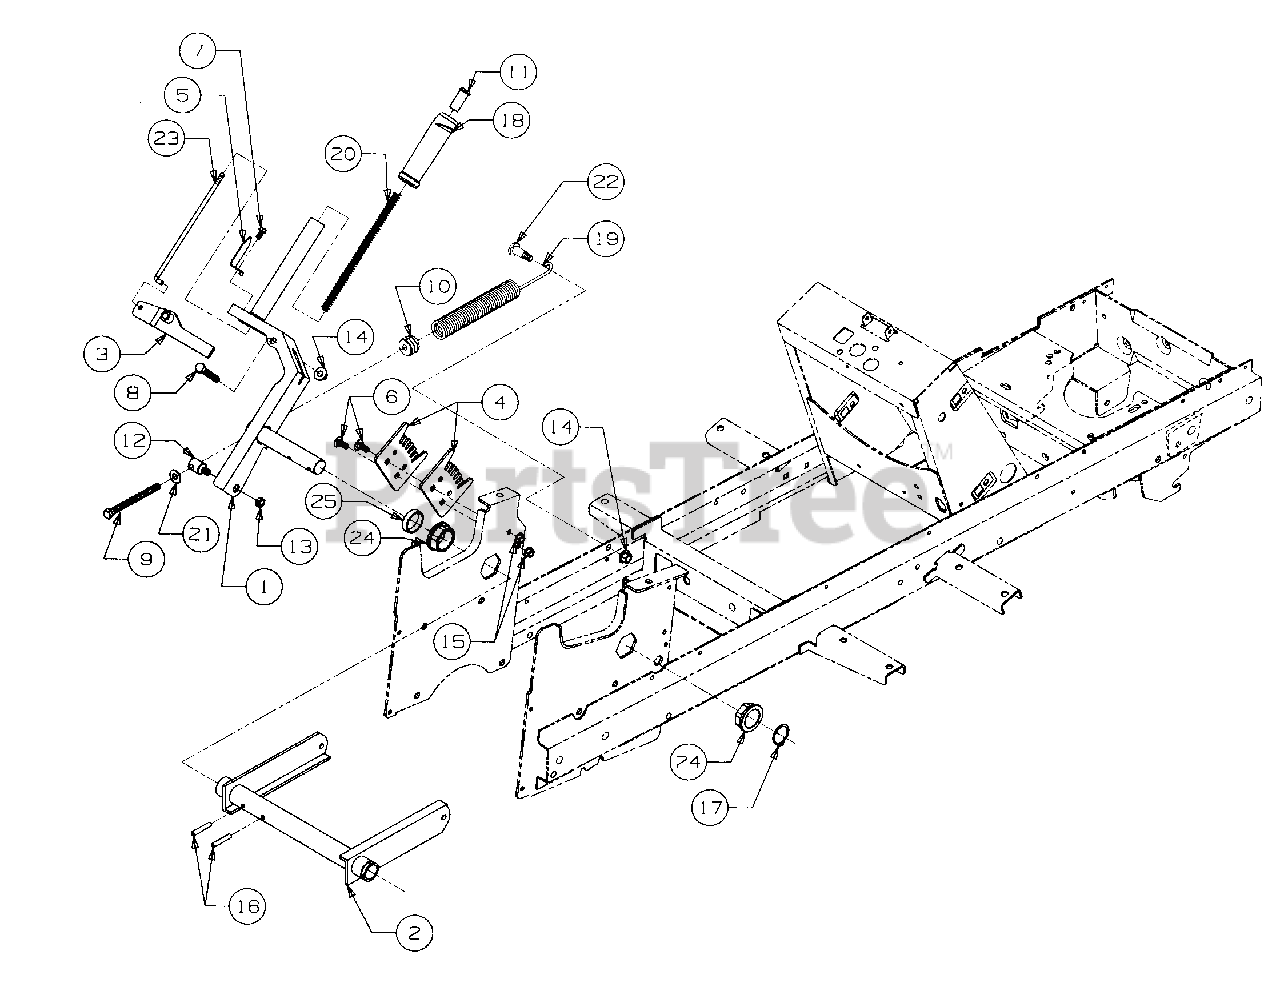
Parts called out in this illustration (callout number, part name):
1	Handle Assembly, Lift
2	Shaft Assembly, Lift
3	Fork, Lift
4	Bracket, Lift Index
5	Indicator, Lift Height
6	Bolt, Carriage, 5/16-18 x .75
7	Screw, Hex Wash Tapp, 1/4 x .5
8	Screw, Hex Cap, 3/8-16 x 2 GR5
9	Screw, Cap, 3/8-16 x 4.25 GR5
10	Insert, Spring
11	Button, Handle
12	Ferrule, Adjustment
13	Nut, Center Lock, Jam, 3/8-24
14	Nut, Hex Flanged Lock, 3/8-16
15	Nut, Flanged Top Lock, 5/16-18
16	Pin, Spiral Spring, 1/4 Dia x 1.5
17	Ring, Snap, 1.25 Dia Shaft
18	Grip, Lift Handle
19	Spring, Extension
20	Spring, Compression
21	Washer, Flat, .385 x .87 x .06
22	Bolt, Shoulder
23	Rod, Index
24	Bearing, Hex Flange, 1.25 ID
25	Spacer, 1.28 ID x 1.5 OD x .335
